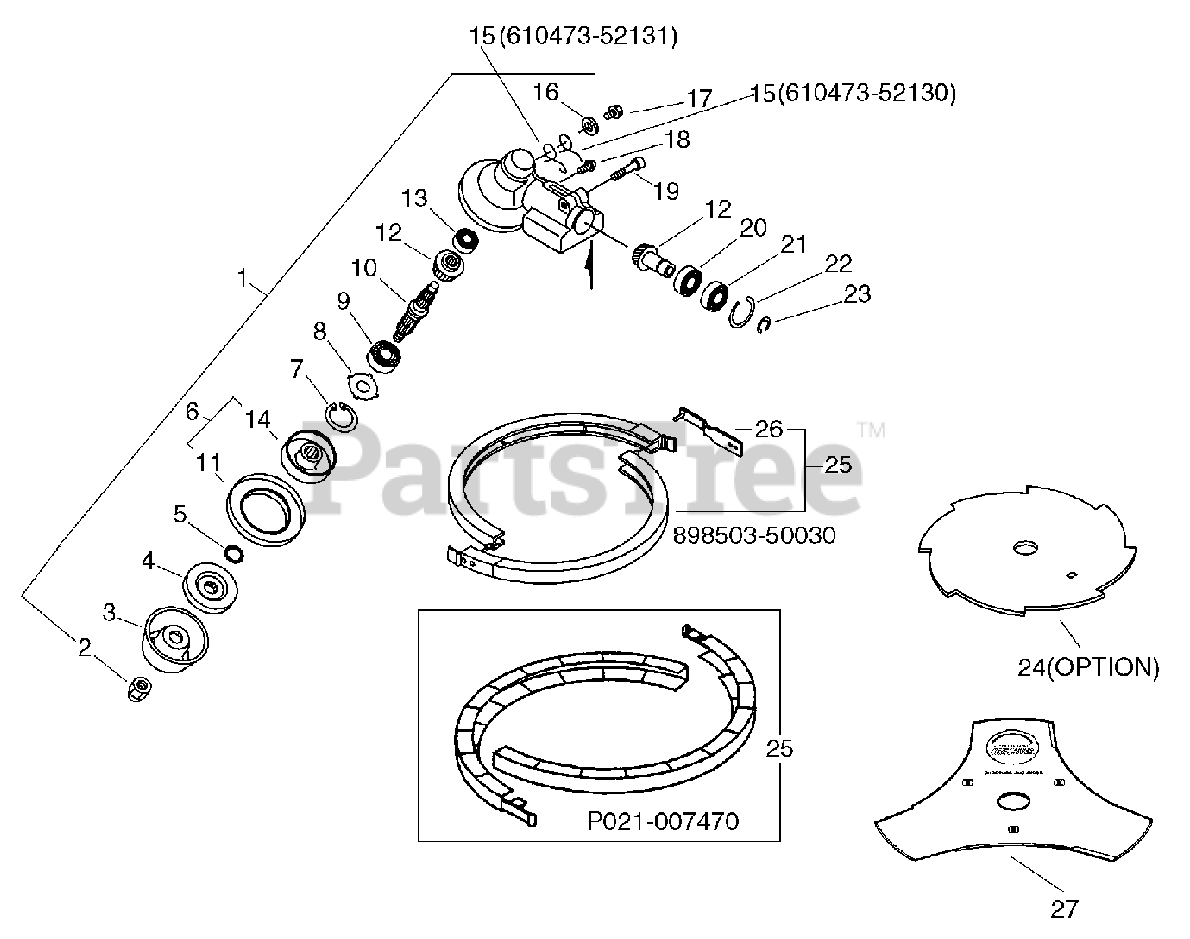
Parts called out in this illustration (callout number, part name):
1	GEAR CASE ASSY
2	NUT - 10
4	ADAPTOR, BLADE - LOWER
5	O-RING - 12
6	ADAPTOR, BLADE - UPPER
6	BLADE ADAPTER KIT
7	RING, RETAINING - 32
9	BEARING, BALL - 6201
10	GEAR - SHAFT
11	PLATE, CUP
12	GEAR SET
13	BEARING, BALL - 629
14	ADAPTOR, BLADE - UPPER
15	SPRING
16	WASHER - 8
17	BOLT - 8X6
17	BOLT - 8X8
18	SCREW - 5X10
19	SCREW - 6X30
20	BEARING, BALL - 6001
21	BEARING, BALL - 6001
22	RING, RETAINING - 28
23	RING, RETAINING - 12
24	BLADE, 8-CUTTER 10IN
25	COVER, BLADE
26	CLAMP
27	BLADE, BRUSHCUTTER
